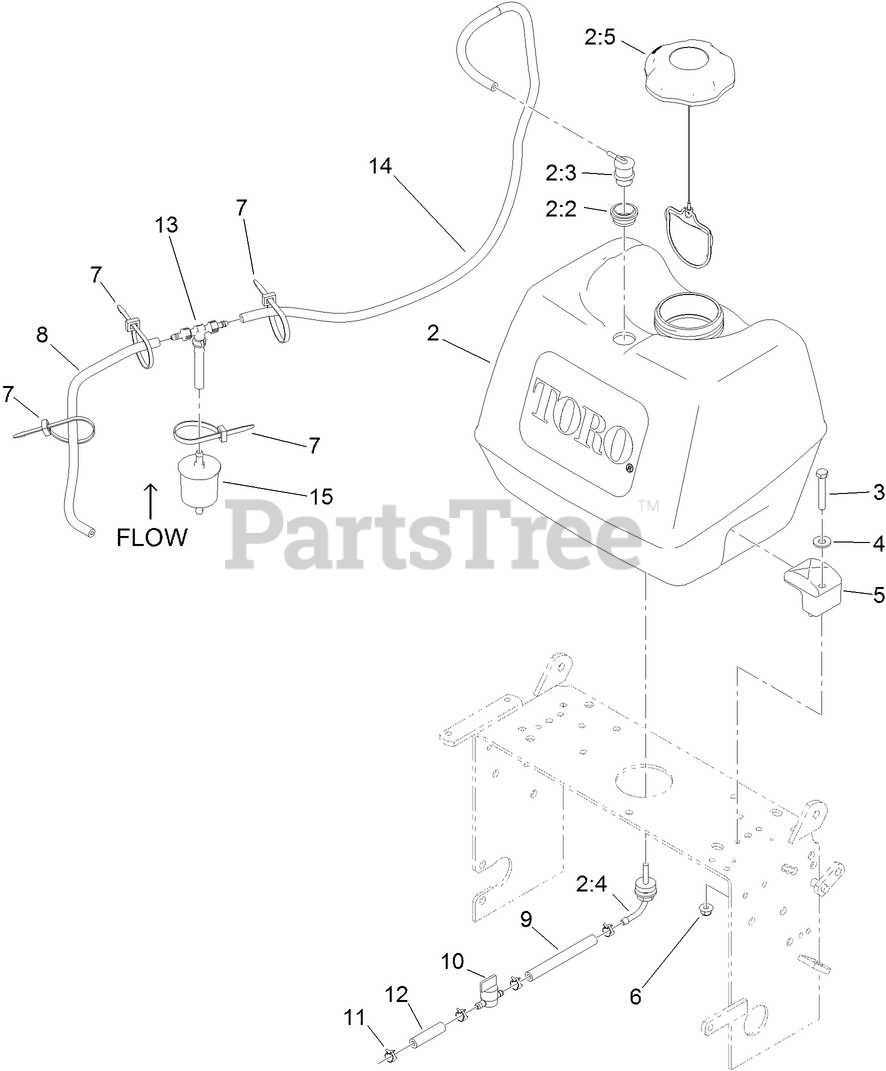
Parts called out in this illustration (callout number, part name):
2	FUEL TANK ASM
2:2	GROMMET
2:3	VALVE-ROLLOVER
2:4	FITTING-FUEL, BULKHEAD
2:5	CAP-FUEL, RATCHETING
3	SCREW-HH
4	WASHER-FLAT
6	NUT-HF, NI
7	TIE-CABLE
8	HOSE-FUEL
9	HOSE-FUEL
10	VALVE-FUEL
11	CLAMP-HOSE
12	HOSE-FUEL
13	TEE AND CHECK
14	HOSE-EMISSIONS
15	FILTER-FUEL
